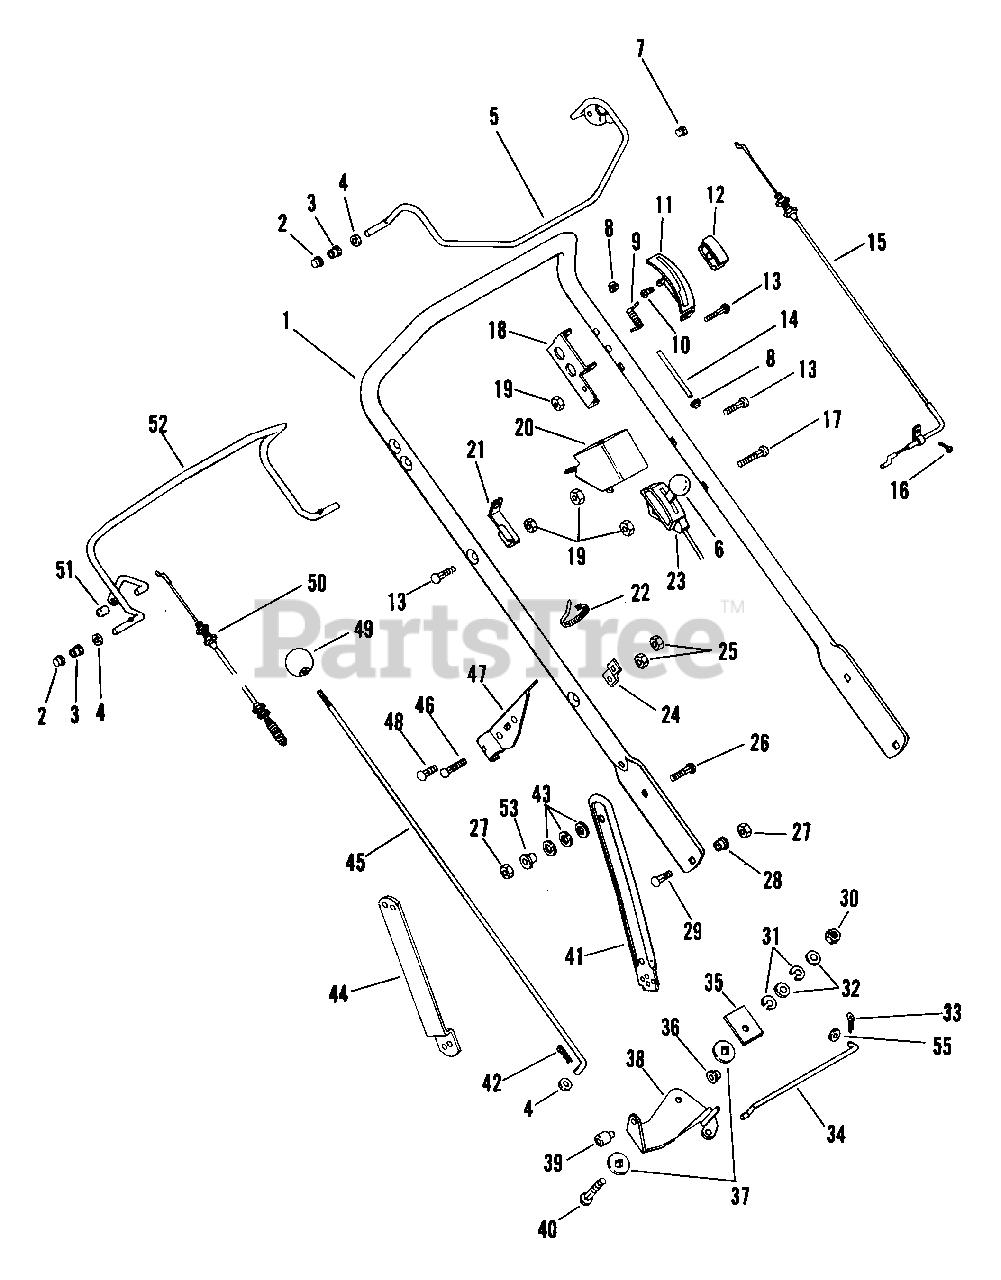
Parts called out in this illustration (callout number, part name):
1	HANDLEBAR
2	NUT-PUSH .312 DIA. PAL
3	BSHG-FLG .325X.444X.440X.560
4	WSHR-FL-STL.344X.688X.065PL
5	START BAIL WELDMENT
5	BBC BAIL
6	KNOB, CONTROL-THROTTLE
7	PUSH NUT, .25
8	PUSH NUT, .188
9	SG-TORS .062X.28X1.00
10	SCR-TAP 10-24X.375 CRPH PL 1A
11	BBC LATCH
12	KNOB
13	BLT-RDHDSQNK .25-20X1.25 XLGPL
14	PIN,BBC LATCH
15	CABLE,ENGINE
15	CABLE-BBC
15	CABLE-ENG. CONTROL
15	CABLE, ENGINE
16	SCR-MCH 10-32X.25 CR SEMS PL
17	BLT-RDHDXLSQNK .25-20X2.0 G5YZ
18	BBC LATCH PIVOT
19	NUT-KEPS .250-20
20	SWITCH-CABLE ANCHOR
21	CABLE ANCHOR
21	CABLE ANCHOR-LH
22	CABLE TIE LG 5-1/2
23	CABLE,THROTTLE W/CHOKE
23	CABLE,THROTTLE
24	BRACE-SPEED CONTROL
25	NUT-LK-CTR .250-20 PL
26	BLT-RDHDSQNK .31-18X1.12 GR5PL
27	NUT-LK-TOP .312-18 GR C PL
28	BSHG, FLG .325X.499X.26X.88
29	BLT-RDHDSQNK.31-18X.88 GR5YWZC
30	NUT-LK-CTR .375-16 GR A PL
31	WSHR-LK .375X.115 HVY PL
32	WSHR-FL-STL.406X.812X.065PL
33	PIN-COTR .06X.50
34	SHIFT LINK
35	PRESSURE FLANGE
36	CAP, 3/8 ROD YWZC
37	FRICTION WASHER
38	BELL CRANK - SPEED CONTROL
39	SWIVEL
40	BLT-RDHDSQNK .38-16X1.50 PL
40	BLT-RDHDSQNK .38-16X1.25 SHTPL
41	LINK,HANDLE BAR ADJUST LH
41	LINK,HANDLE BAR ADJ RH
42	PIN-HAIR INT .08X.18X1.18
43	WASHER,BELLEVILLE SPRING
44	HANDLEBAR BRACKET
45	ROD-SPEED CONTROL
46	BLT-RDHDSQNK .25-20X1.38SHT PL
47	BRACKET-SPEED CONTROL
48	@BLT-RHDSSQNK .25-20X.38 G2YZ
49	KNOB, BALL 5/16-18 X 1.5
50	CABLE, TRACTION
51	CAP, VINYL, .25 ID
52	TRACTION BAIL-COATED
53	BSHG-FLG .325X.500X.513X.875
54	SPACER
55	WSHR-FL-STL.281X.62X.065 PL
